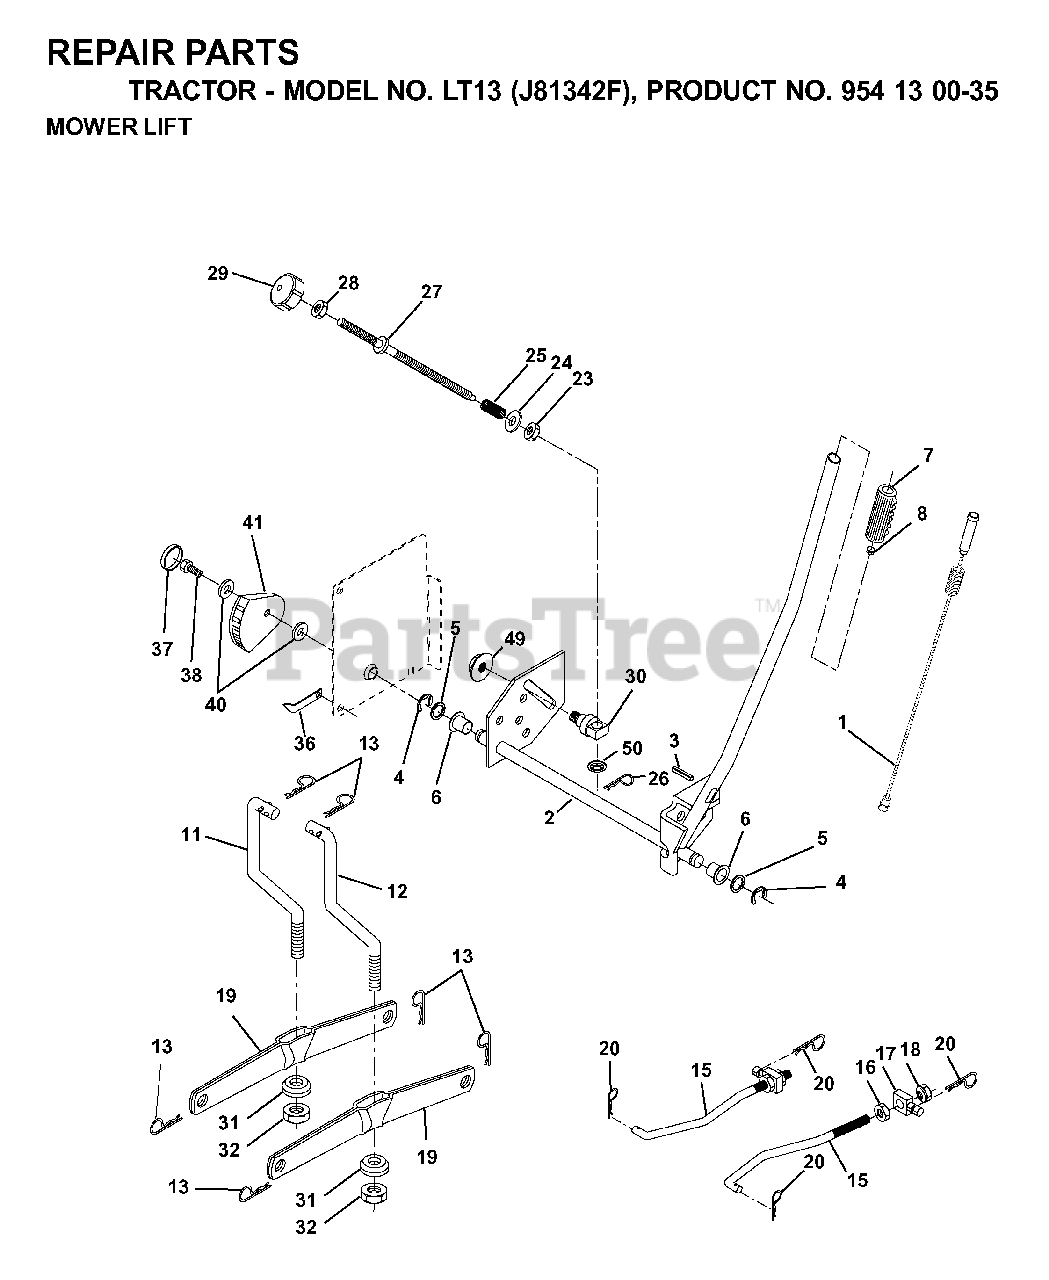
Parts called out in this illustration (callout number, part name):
1	WIRE ASM INNER W/ PLUNGER LT
2	SHAFT ASM R HANDLE
3	PIN GROOVE
4	RETAINING RING LT
6	BEARING.NYLON
7	GRIP HANDLE
11	LINK LIFT LH
12	LINK LIFT RH
13	RETAINER-SPRNG RB
15	LINK.SUSPENSION.FRONT
16	NUT
17	TRUNION
18	NUT
19	ARM.REAR.SUSPENSION
20	SPRING RETAINER
25	SPRING**
26	RETAINER CLIP
27	ROD ADJ LIFT
28	NUT
29	KNOB INF 3/8-16
31	BEARING PIVOT
32	NUT CROWNLOCK 3/8-24
36	POINTER, HEIGHT INDICATOR
37	PLUG,HOLE
38	SCREW 5/16-18X1
41	IND. HEIGHT STLT
49	NUT
50	NUT PUSH M
51	RETAINER-SPRNG RB
